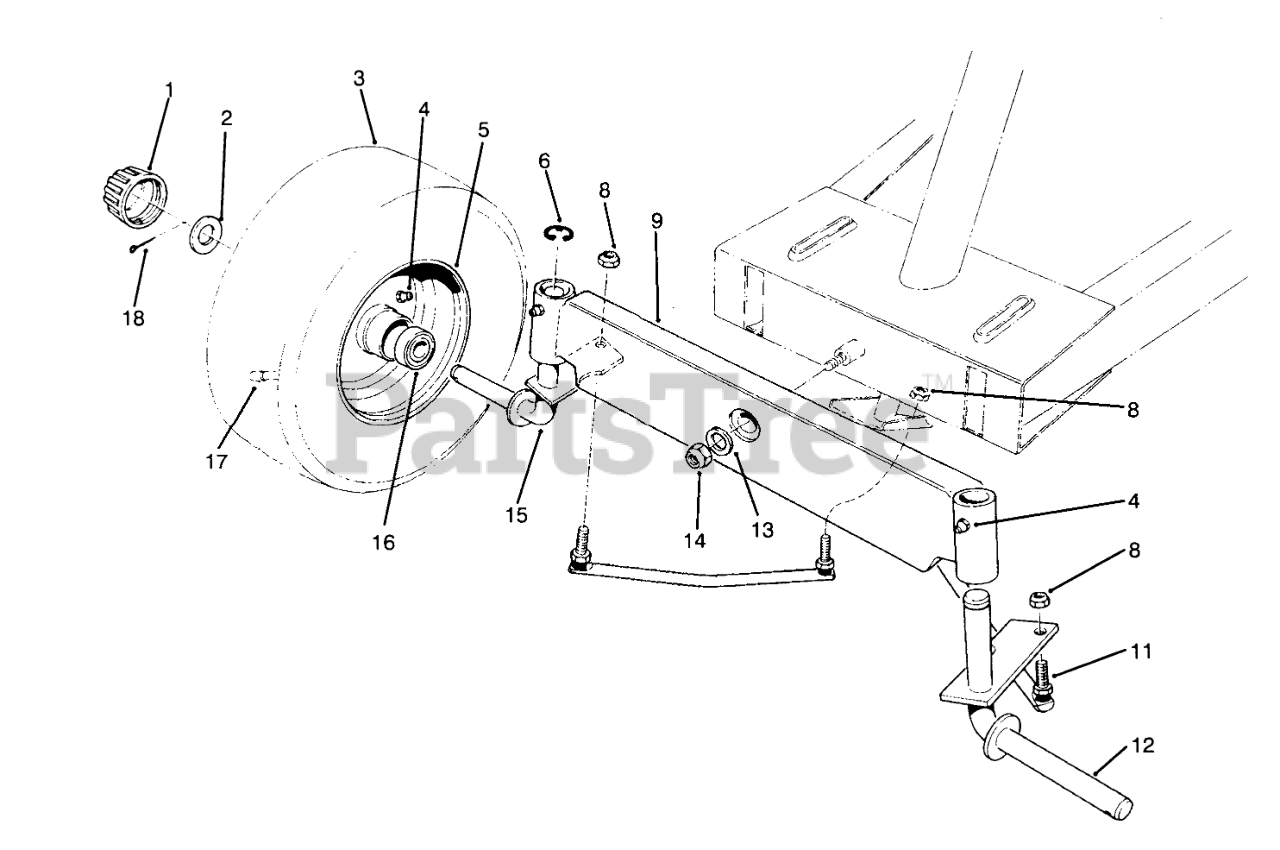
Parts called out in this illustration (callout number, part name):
1	CAP-HUB
2	WASHER-PLAIN
3	TIRE,PNEU.11X4.00X5
4	FITTING-GREASE
6	E-RING
8	NUT-LOCK
9	Axle-Front
11	TIE ROD ASM
12	WHEEL SPDLE WA LH (RED)
13	WASHER-FLAT
14	NUT-LOCK, NI
15	WHEEL SPDLE WA RH (RED)
16	BEARING-WHEEL
17	STEM-VALVE
18	PIN-COTTER
